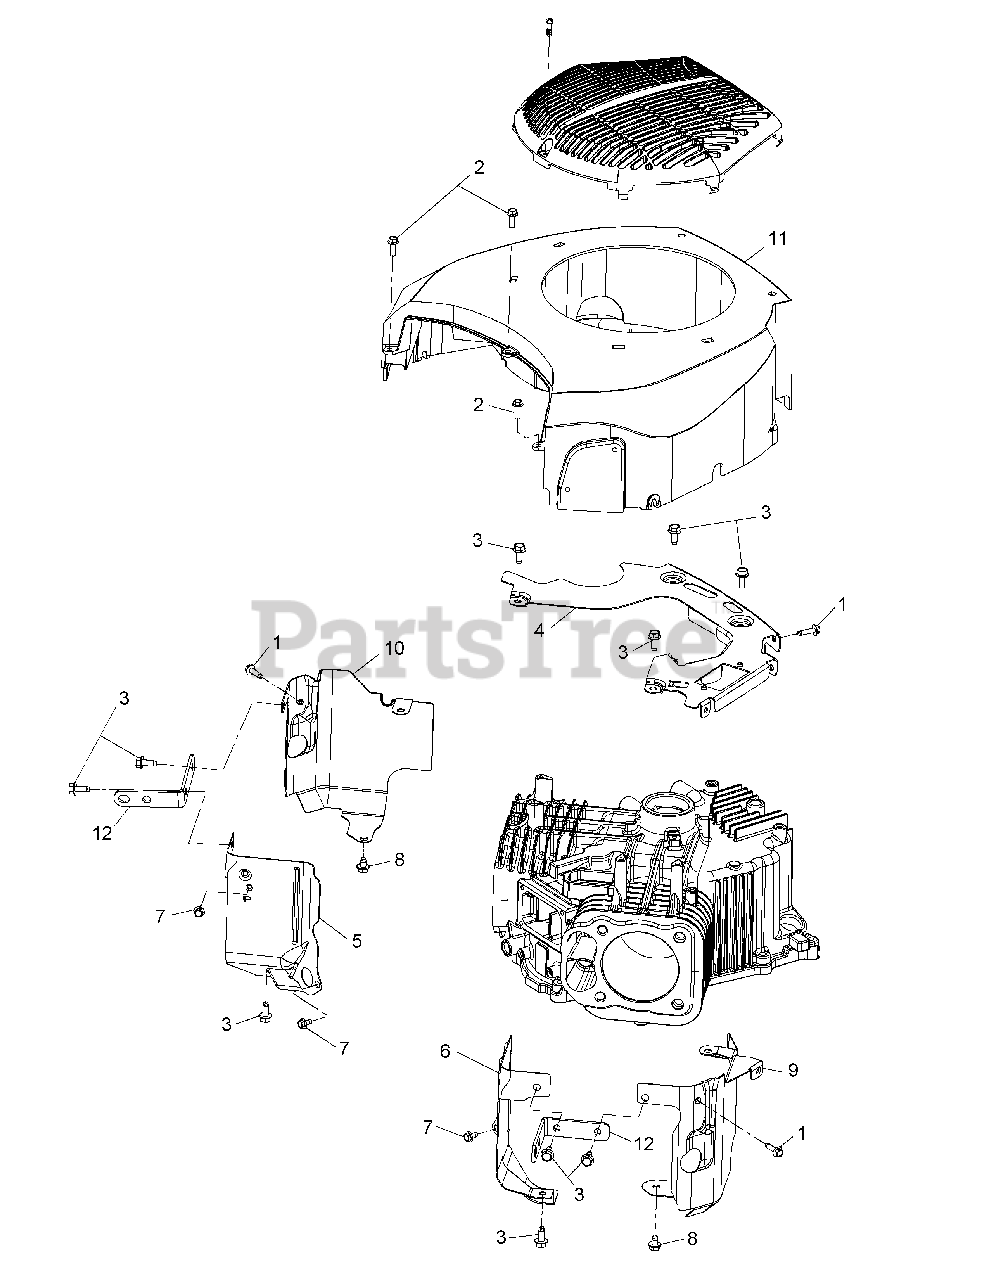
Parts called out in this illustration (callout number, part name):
1	Thread Forming Screw
3	Thread Forming Screw
4	Backing Plate
5	Valley Baffle, #1 Cylinder
6	Valley Baffle, #2 Cylinder
7	Thread Forming Screw
8	Thread Forming Screw
9	Left Barrel Baffle
10	Right Barrel Baffle
11	Blower Housing
